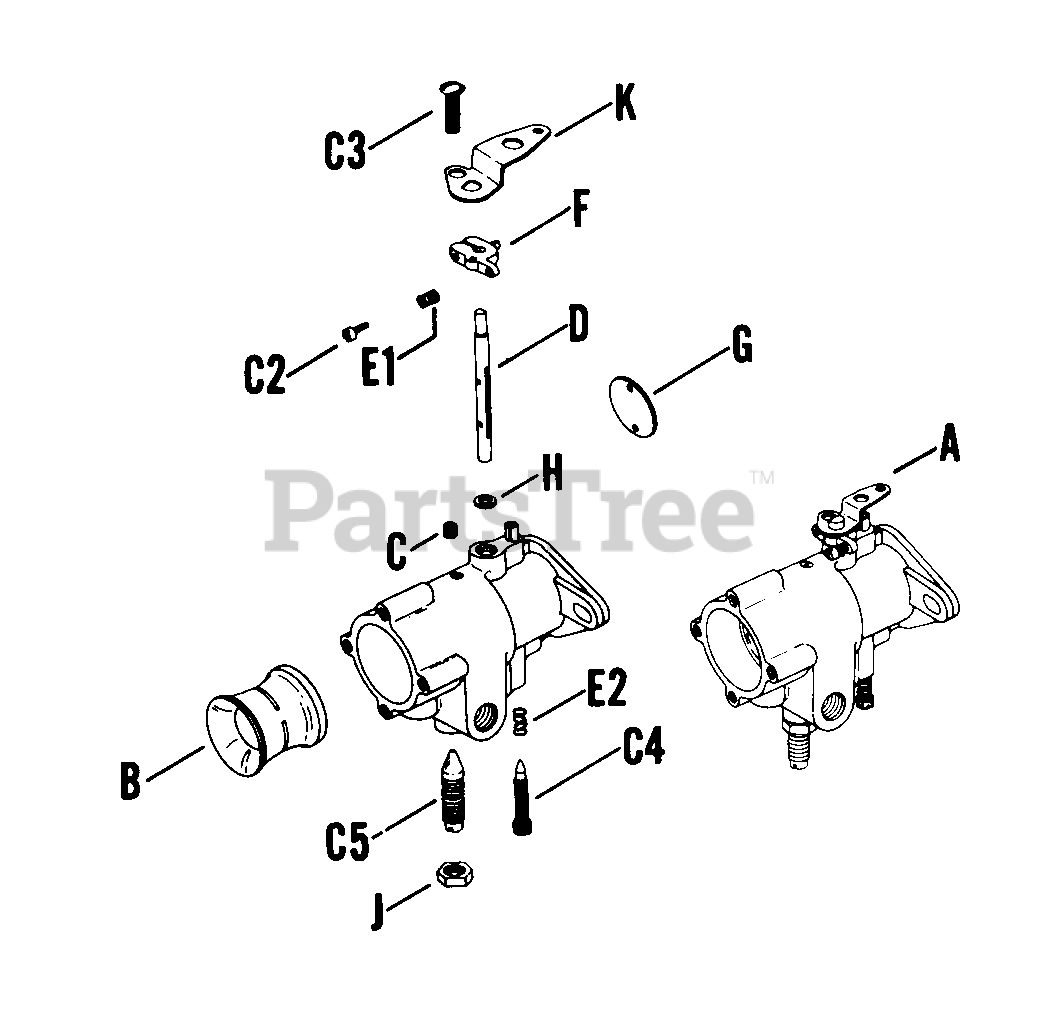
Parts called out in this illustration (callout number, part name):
A	CARBURETOR - DISCONTINUED
C3	KIT - DISCONTINUED
C4	SCREW - DISCONTINUED
E1	SPRING - DISCONTINUED
E2	SPRING - DISCONTINUED
H	SEAL - USE 235450
K	LEVER - DISCONTINUED
